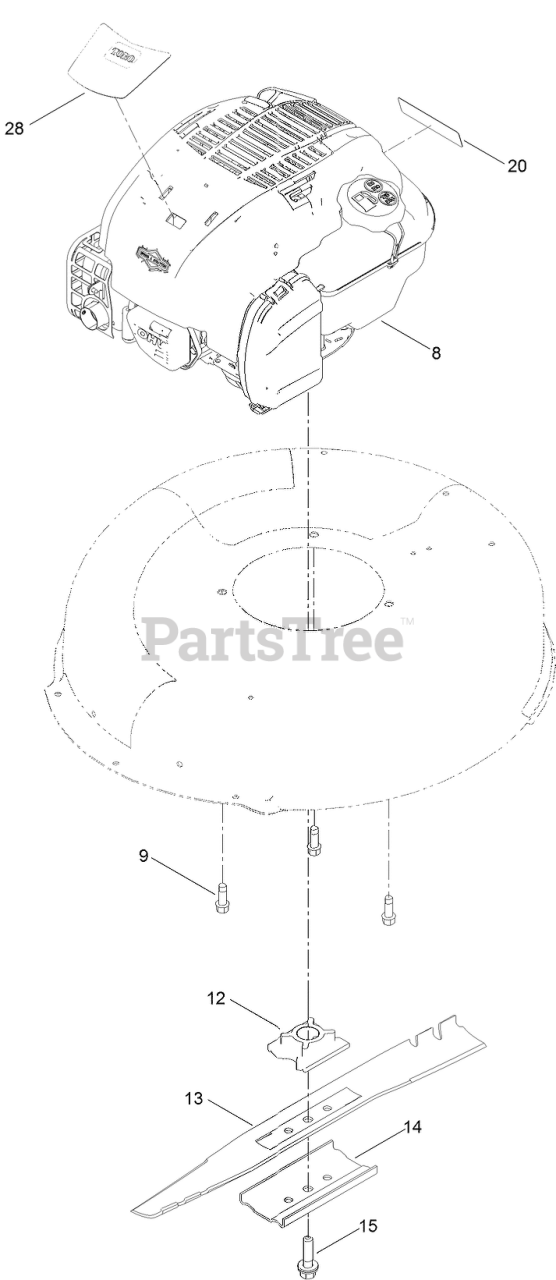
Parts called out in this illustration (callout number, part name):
9	SCREW-TAPTITE
12	RETAINER-BLADE
13	BLADE-21IN
14	SUPPORT-BLADE
15	BOLT-BLADE
20	DECAL-ARRESTER, SPARK
28	DECAL-ENGINE
